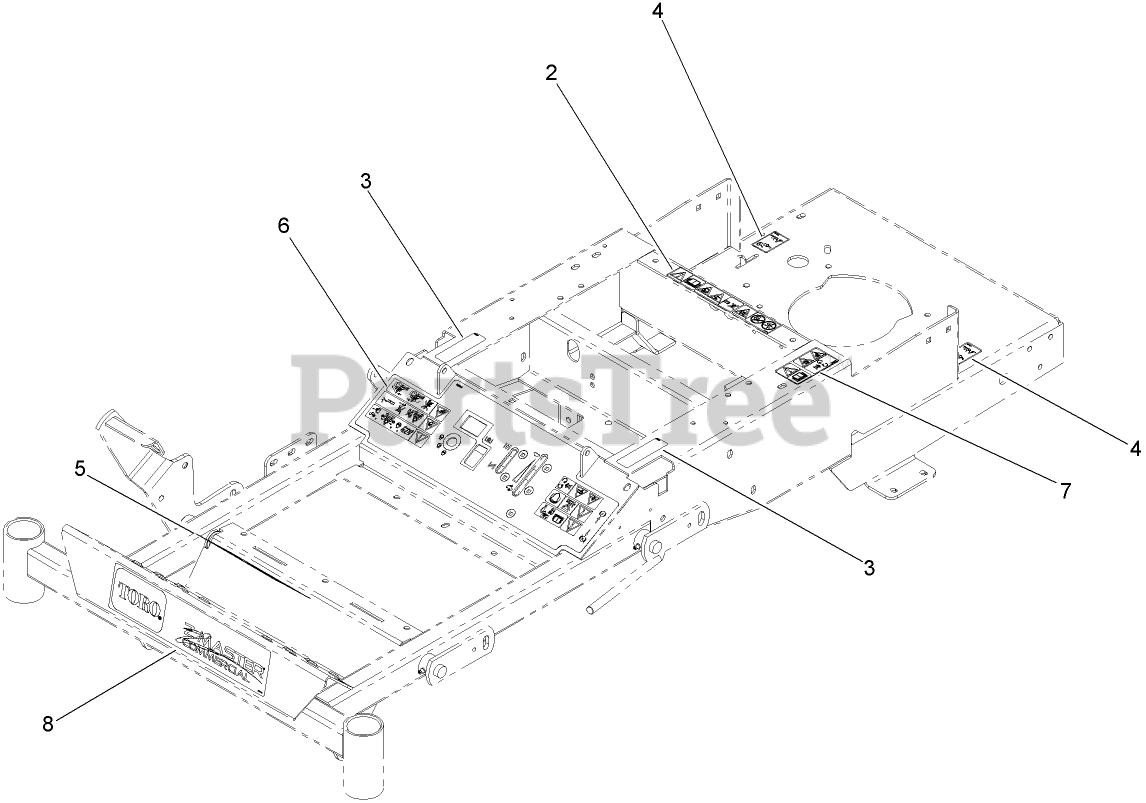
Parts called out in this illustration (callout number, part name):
2	DECAL-DANGER BATTERY, CE
3	DECAL-CONTROL, MOTION
4	DECAL-TRANSPORT, CE
5	DECAL-DANGER SLOPE, CE
6	DECAL-CONSOLE, CE
7	DECAL-DANGER, CE
